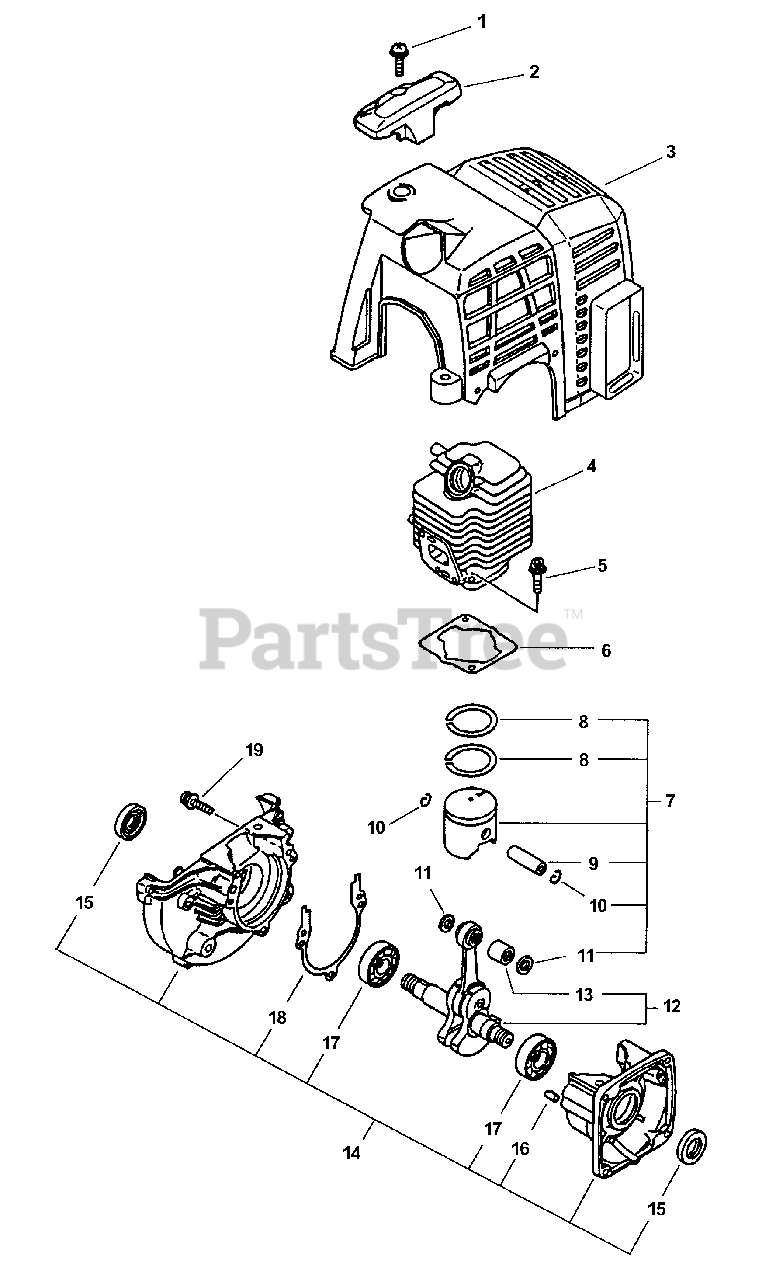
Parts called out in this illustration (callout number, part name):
1	SCREW - 5X16
2	GUARD - TOP
3	COVER, ENGINE
4	CYLINDER
5	SCREW - 4X16
6	GASKET, CYLINDER
7	PISTON KIT
8	RING, PISTON
9	PIN, PISTON
10	RING, RETAINING
11	SPACER, PISTON
12	CRANKSHAFT ASSY
13	BEARING, NEEDLE
14	CRANKCASE KIT
15	SEAL, OIL
16	PIN - LOCATING
17	BEARING, BALL - 6201
18	GASKET, CRANKCASE
19	SCREW - 5X28
